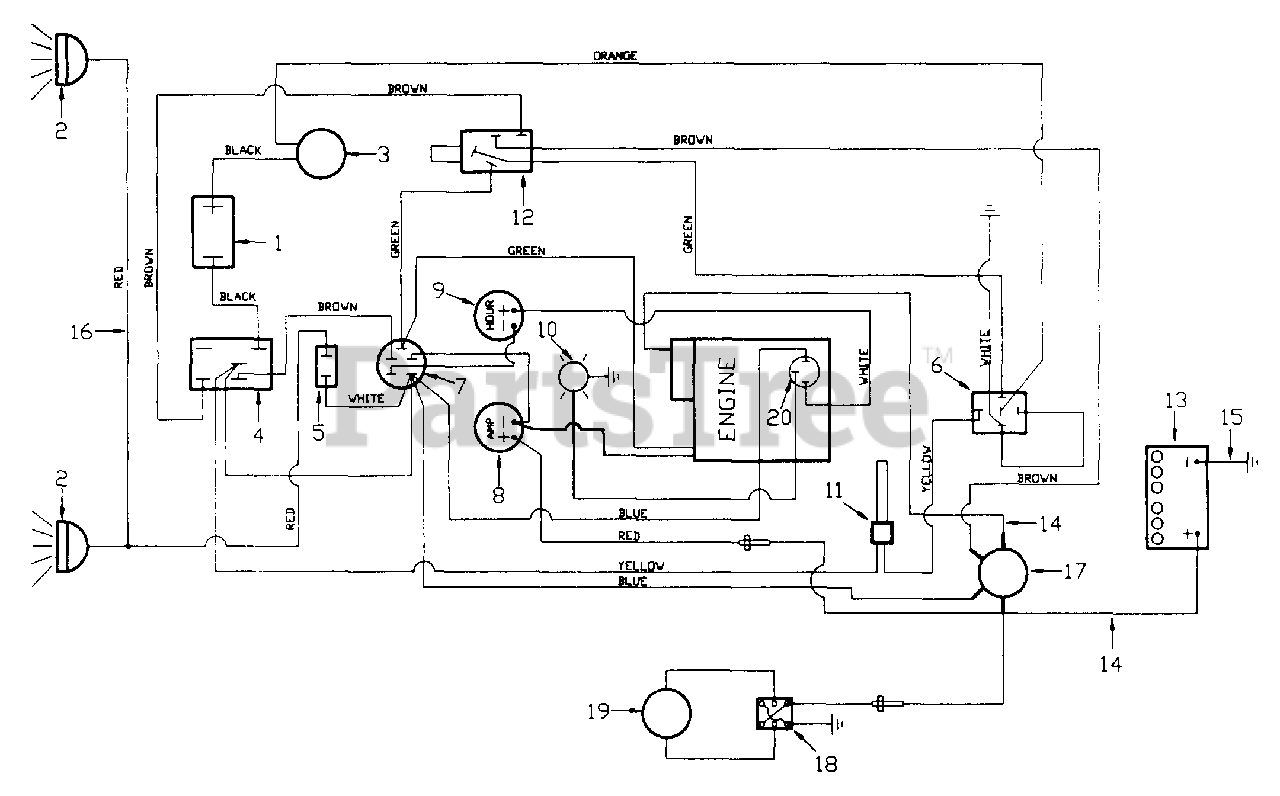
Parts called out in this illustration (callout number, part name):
1	10 Amp Circuit Breaker
2	Headlight Assembly
3	Electric Clutch Assembly
4	PTO Clutch Switch
5	Light Switch
6	Relay
7	Ignition Switch
13	Battery
16	Light to Switch Wire
18	3 Position Deck Lift Switch
19	Electric Lift Actuator
20	Oil Sending Unit
